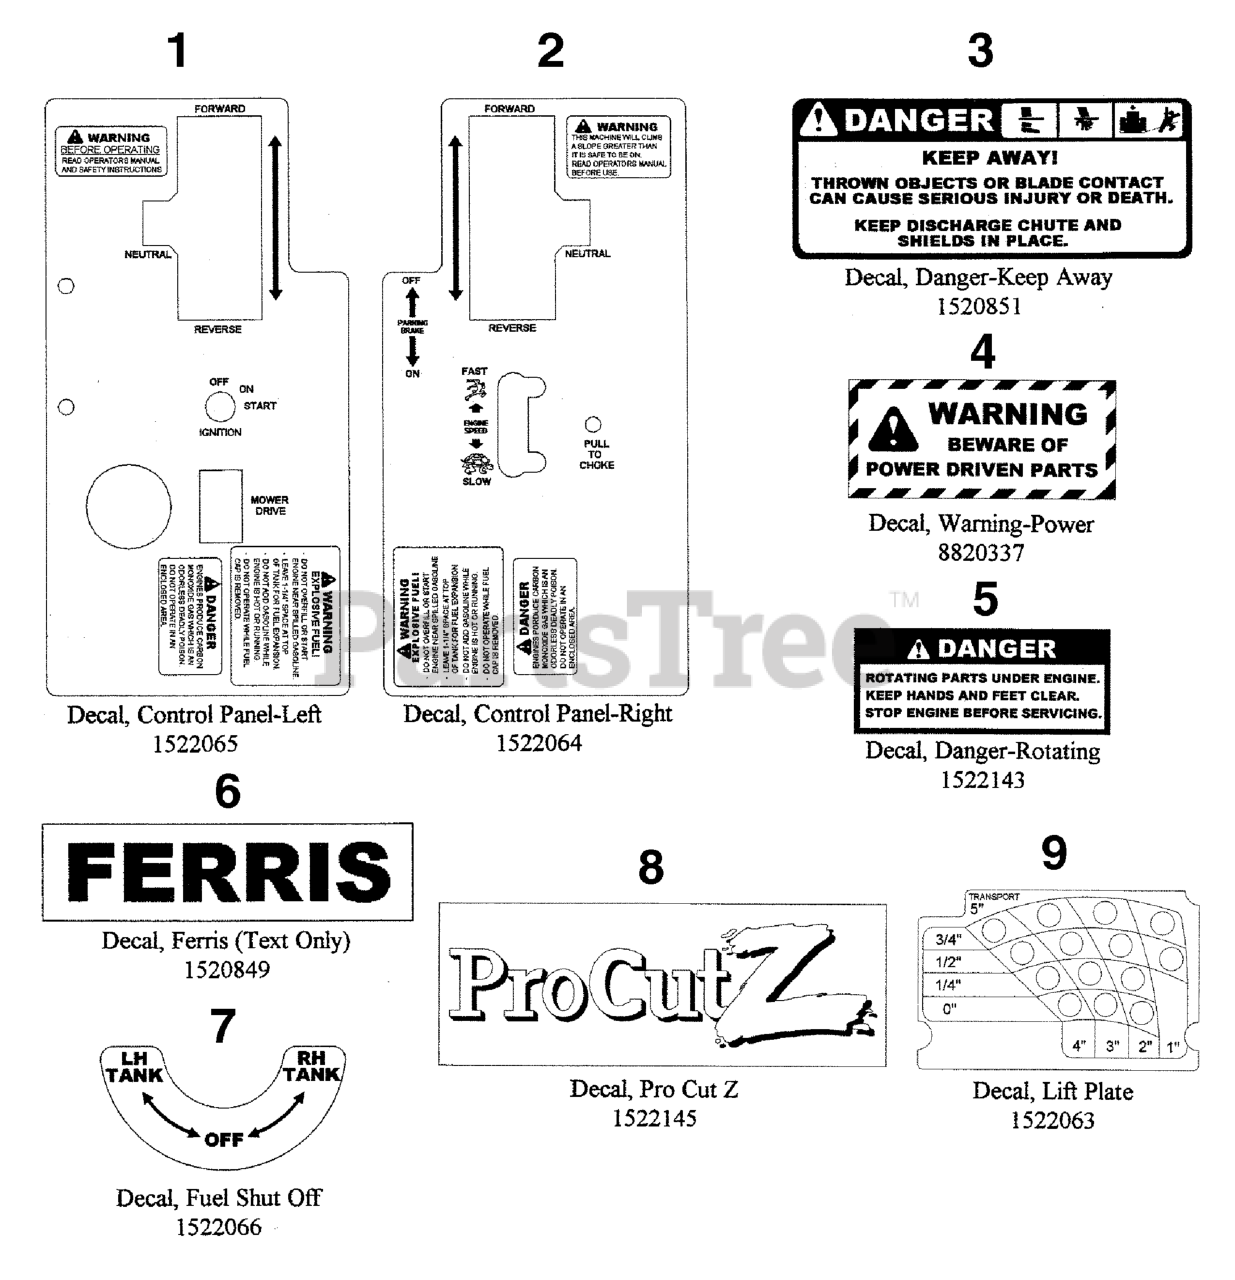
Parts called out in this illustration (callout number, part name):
1	DECAL, Control Panel, Left
2	DECAL, Control Panel, Right
3	DECAL, DANGER DO NOT OPERATE W/O DEFLECT
4	DECAL, Warning
5	DECAL, Danger, Rotating
6	DECAL, FERRIS TEXT & LOGO
7	DECAL, Fuel Shut Off
8	DECAL, Pro Cut Z
9	DECAL, Deck Height
